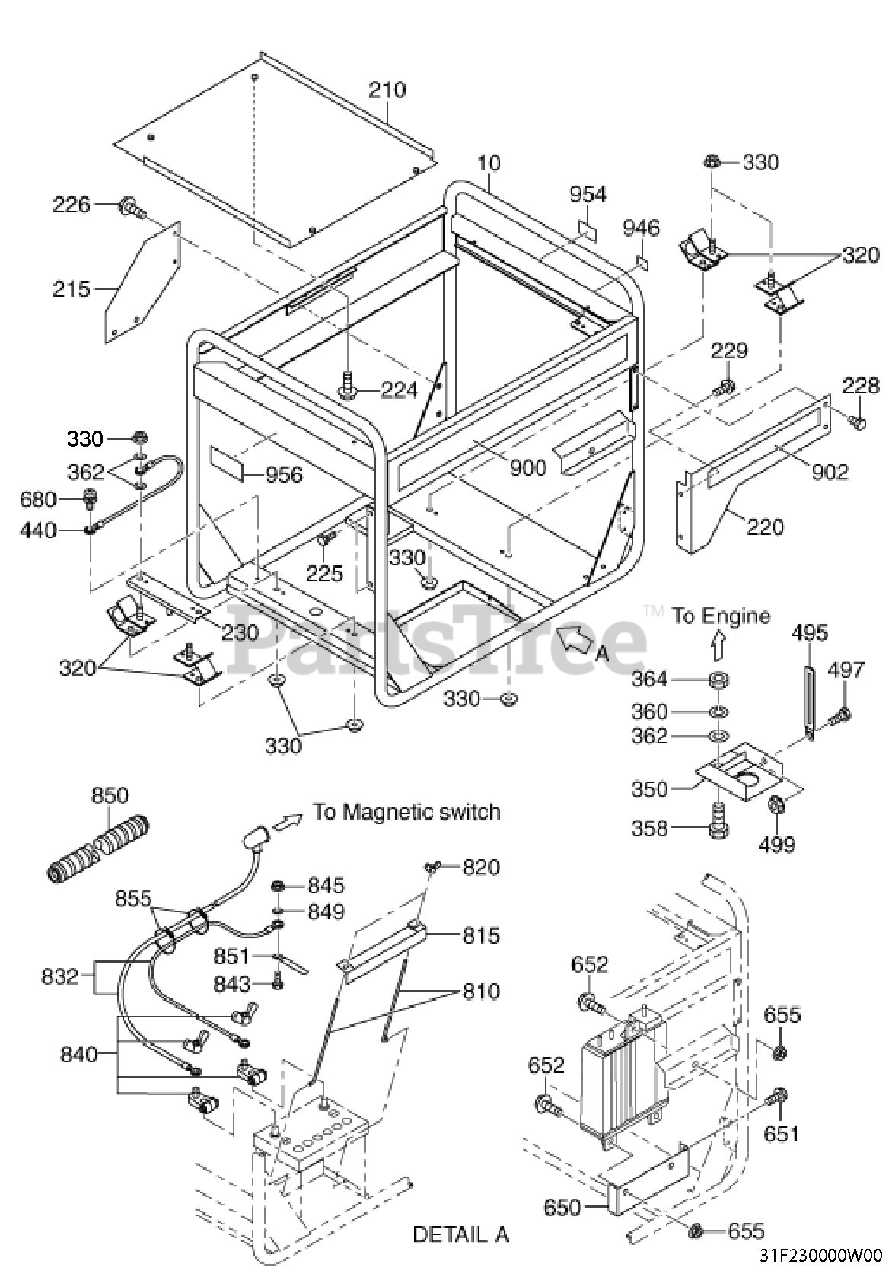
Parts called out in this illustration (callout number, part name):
10	PIPE FRAME CP
224	FLANGE BOLT
228	SCREW AND WASHER AY
229	FLANGE BOLT
230	GENERATOR BASE
330	FLANGE NUT
360	SPRING WASHER
362	WASHER
495	CLAMP
497	FLANGE BOLT
499	FLANGE NUT
650	BRACKET, CANISTER
652	FLANGE BOLT
655	FLANGE NUT
680	SCREW
815	BATTERY STAY CP
832	WIRE CABLE SET
840	BATTERY TERMINAL
843	BOLT AND WASHER AY
845	FLANGE NUT
849	WASHER
850	CORRUGATED TUBE
851	CLAMP
855	WIRE BAND
900	LABEL, TRADE MARK
902	LABEL (RGV12100)
946	LABEL (F. STRAINER)
954	LABEL (CHOKE)
956	LABEL (HOT & GAS)
